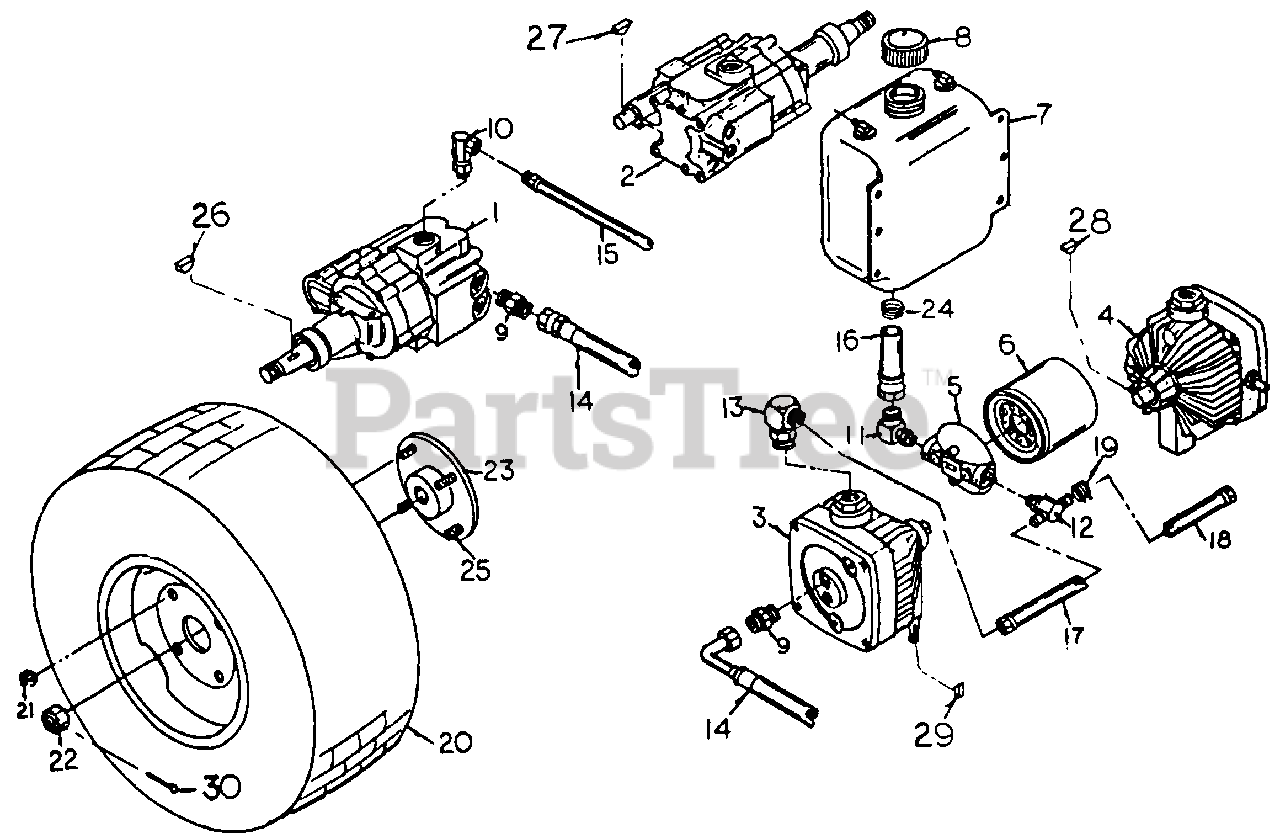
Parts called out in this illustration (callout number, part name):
1	Wheel Motor, LH
2	Wheel Motor, RH
3	Pump, LH
4	Pump, RH
5	Housing, Oil Filter
6	Element, Oil Filter
7	3 Qt. Oil Tank
9	Male Tube, Male O-ring Adp.
10	Male O-ring, 90° Female Pipe Swivel Adp.
11	Male O-ring, 90° Male Tube Adp.
12	Male O-ring, 1/2" Hose Barb Tee
13	Male O-ring, 90° Male Tube Adp.
14	Hose, 1/2" ID x 28" Long
15	Hose, 1/4" ID x 24" Long, Easy Couple
16	Hose, 5/8" ID x 3 3/4" Long, Easy Couple
17	Hose, 1/2" ID x 7 3/4" Long, Easy Couple
18	Hose, 1/2" ID x 12" Long, Easy Couple
19	Hose Clamp, 1/2"
20	Wheel Ass'y., 18 x 9.50-8
20	Wheel Ass'y., 18 x 6.50-8
21	Lug Nut, 1/2-20
22	Nut, Wheel Motor
23	4-Bolt Wheel Hub
24	Hose Clamp, 5/8"
25	Lug Bolt, 1/2-20 x 1 1/4"
26	Woodruff Key, 1/4" x 1"
27	Woodruff Key, 3/16" x 3/4"
28	Woodruff Key, 1/8" x 1/2"
29	Woodruff Key, 1/8" x 3/8"
30	Cotter Pin, 1/8" x 1 3/4"
